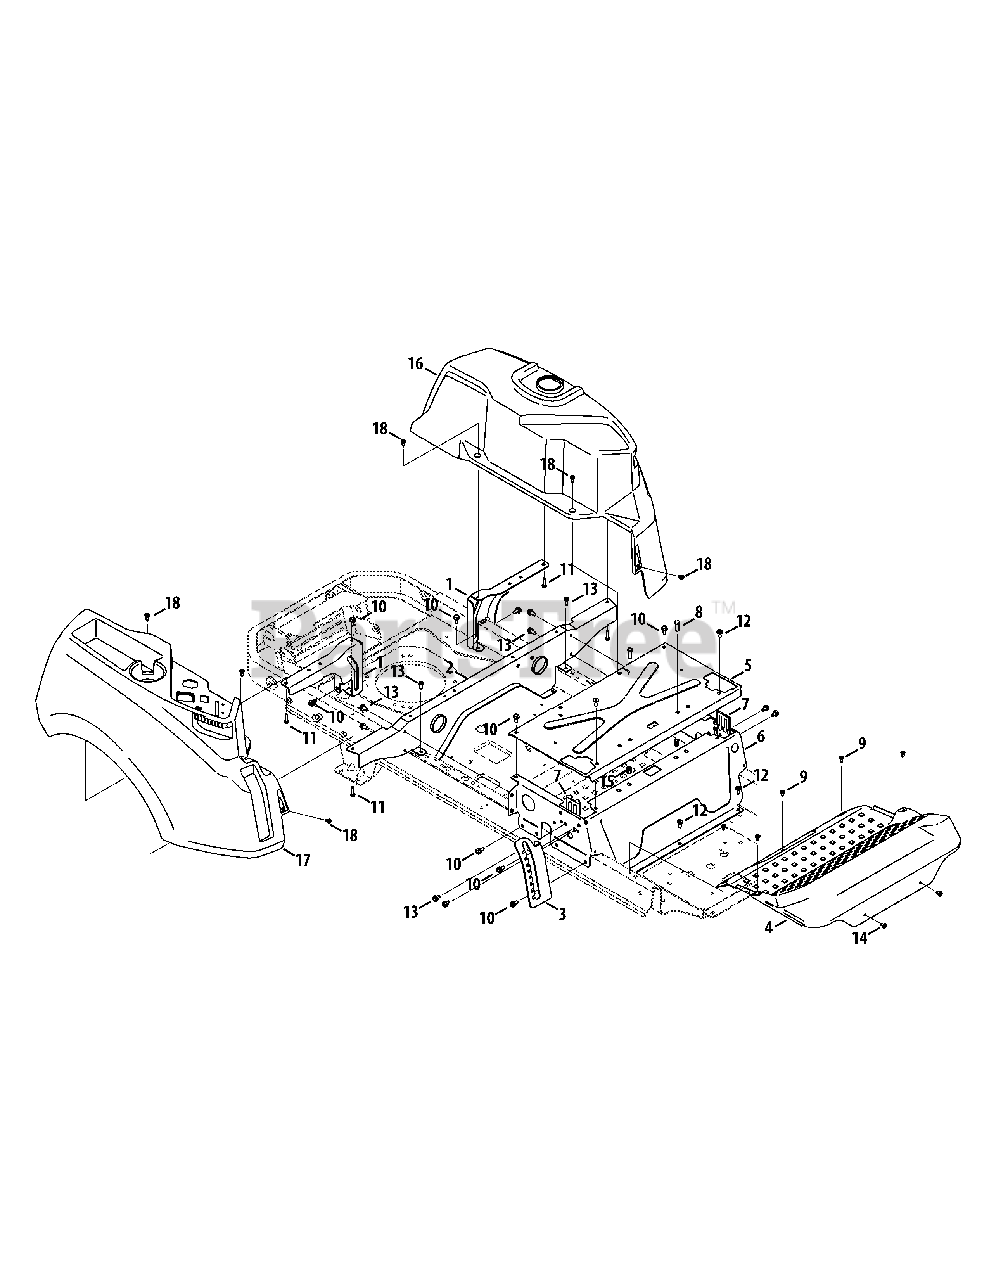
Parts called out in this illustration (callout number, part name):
1	Rear Tank Bracket
2	Rear Seatbox Brace
3	Height Index Bracket
5	Seatbox Plate
6	Seat Frame
7	Lapbar Brace Bracket
8	Hex Cap Screw, 5/16-18 x 1.00
9	Self Tapping Screw, 1/4-20 x .50
10	Hex Washer Screw, 5/16-18 x .750
11	Hex Washer Screw, 5/16-14 x 1.00
12	Self Tapping Screw, 5/16-18 x .750
13	Hex Washer Screw, 5/16-18 x .50
14	Screw, Self-Tapping, 5/16-18, 0.750
15	Nut, 5/16-18
16	LH Console
17	RH Console
18	Shoulder Screw, 1/4-20
